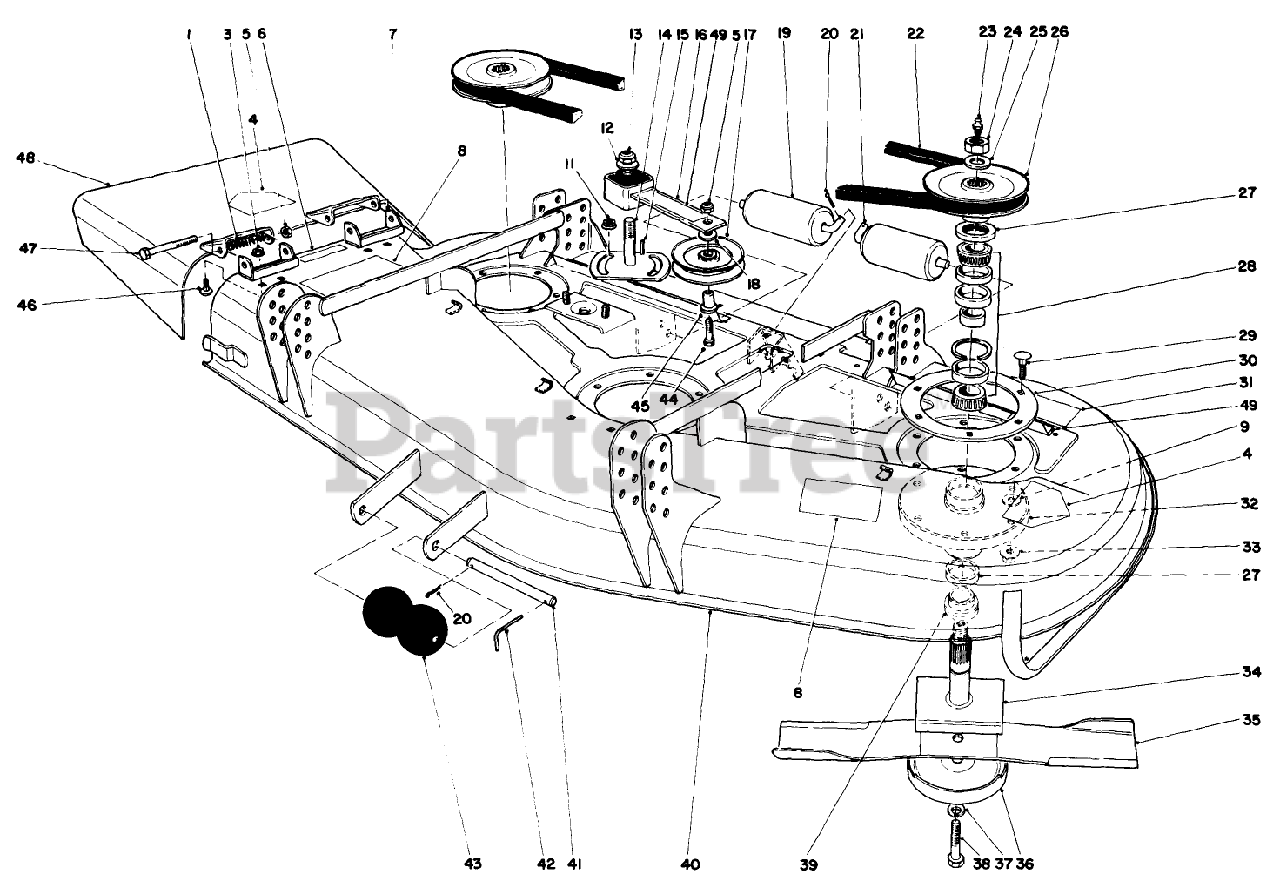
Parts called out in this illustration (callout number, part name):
1	SPRING
3	NUT-HF
4	DECAL-DANGER
5	NUT-HEX
6	DECAL-DANGER
6	FITTING-GREASE, 90 DEG
7	Bracket-Pivot
8	DECAL-DANGER, THROWN OBJECT
9	WASHER-FLAT
11	NUT-HHF, WHIZ
12	WASHER-FLAT
13	NUT-LOCK, NI
14	PLATE-IDLER
15	KEY-SQUARE
16	IDLER ARM ASM
17	PULLEY-IDLER
18	WASHER-FLAT
19	ROLLER-DECK
20	PIN-COTTER
21	SHAFT-ROLLER, REAR
22	V-BELT
23	FITTING-GREASE
24	NUT-HEX
25	WASHER
26	PULLEY AND HUB ASM
27	SEAL-OIL
28	BEARING ASM
29	SCREW-CARR
30	SUPPORT-DECK, RING
31	DECAL-TORQUE
32	HOUSING-SPINDLE
33	NUT-HF
34	SHAFT
35	Blade
36	CUP-SCALP, ANTI
37	WASHER-LOCK
38	SCREW-BLADE
39	SPACER
40	Cutting Deck
41	SHAFT-ROLLER
42	PIN-SPECIAL
43	ROLLER
44	SCREW-HH
45	BUSHING-PULLEY
46	SCREW-CARR
47	SCREW-HH
48	Deflector-Grass (Incl. Ref. #4)
49	DECAL-DANGER
